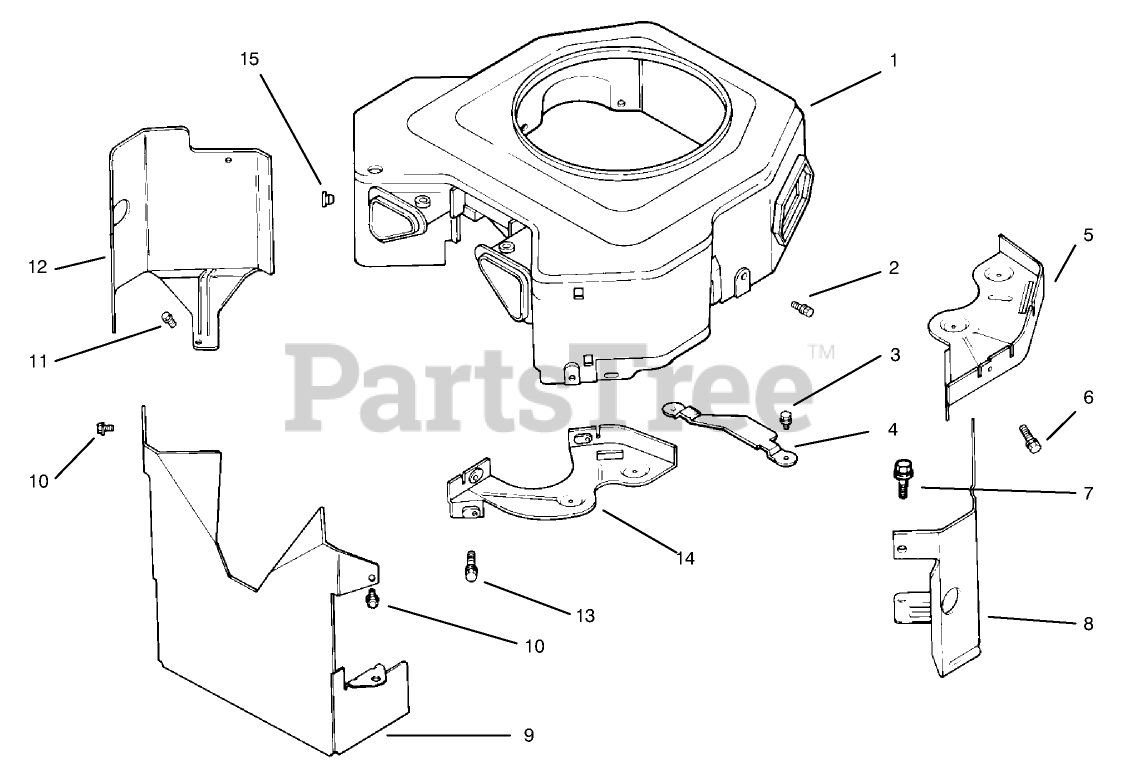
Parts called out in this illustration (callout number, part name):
1	Housing-Blower
2	Screw
3	Screw
4	Guard-Flywheel
5	Plate-Backing #2 Side
6	Screw
7	Screw
8	Baffle-Cylinder, #2
9	Baffle-Valley
10	Screw
11	Screw
12	Baffle-Cylinder #1 Side
13	Screw
14	Plate-Backing #1
15	Nut-Plastic
